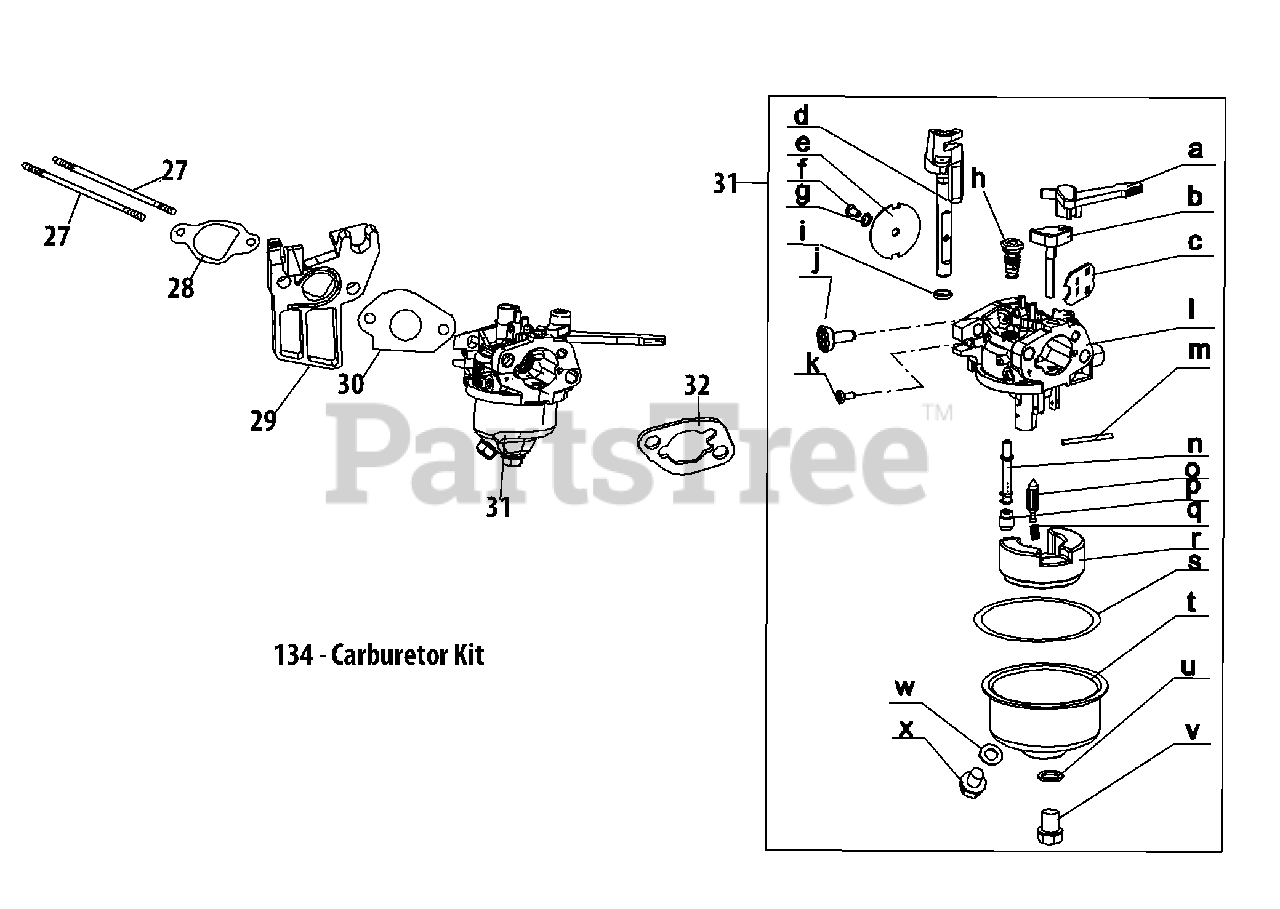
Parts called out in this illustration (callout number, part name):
27	Stud M6×110
28	Carburetor Insulator Gasket
29	Carburetor Insulator
30	Carburetor Gasket
31	Carburetor Assembly
32	Carburetor Gasket Plate
134	Carburetor Rebuild Kit
